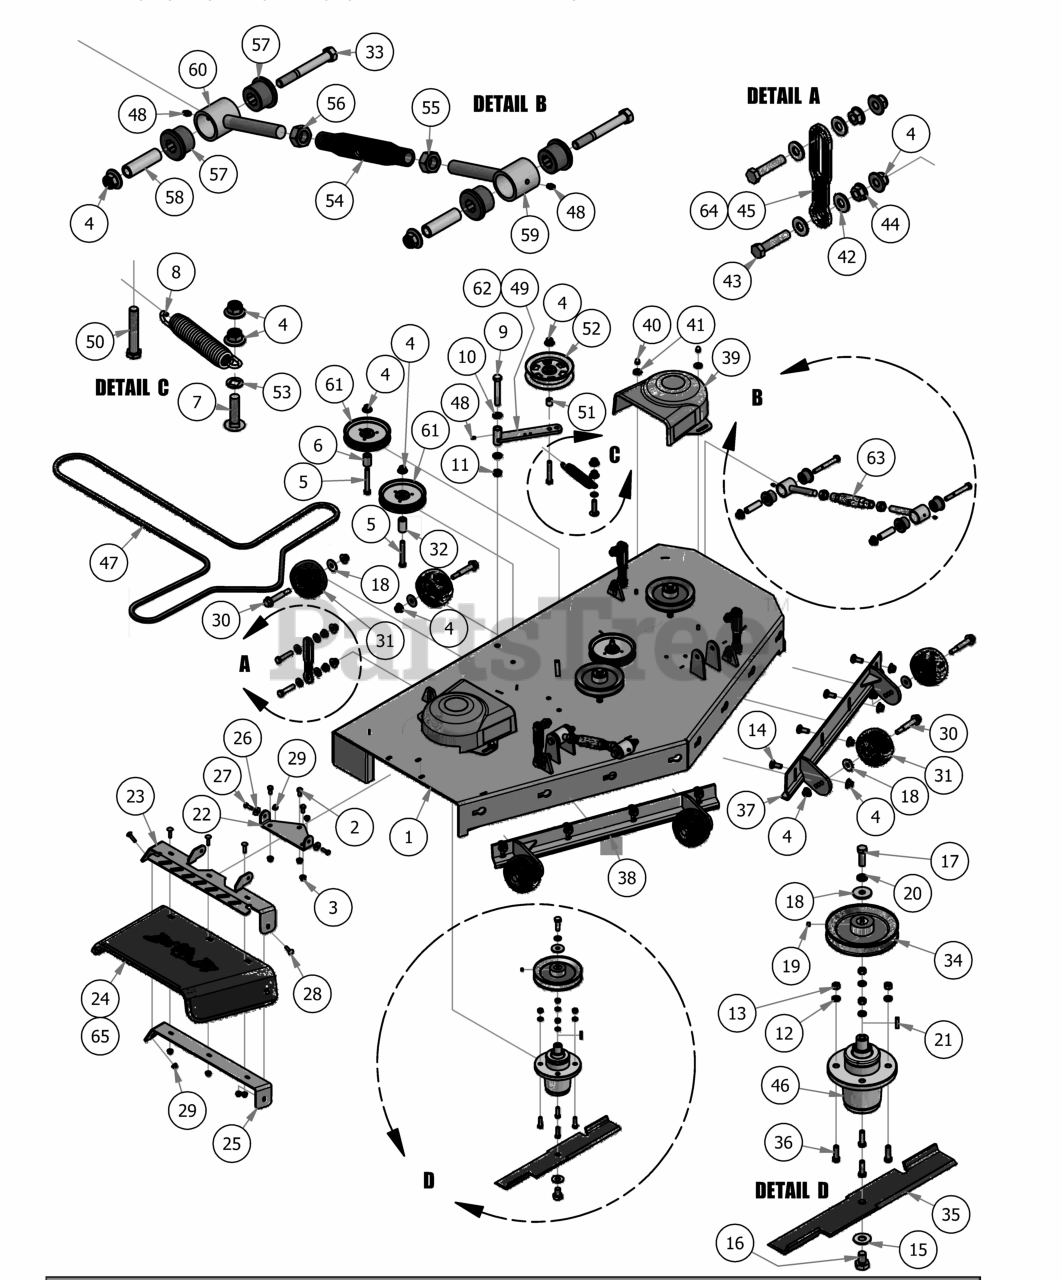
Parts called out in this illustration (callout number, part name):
1	2015 61" Deck
2	3/8" x 3/4" Hex Bolt
3	3/8" Flange Nut
4	1/2-13 Nylon Flange Nut
5	1/2 x 3 1/2 Flange Bolt Grade 8
6	Idler Pulley Standoff
7	1/2 x 2" Carriage Bolt
8	Deck Idler Spring
9	5/8" x 4" Hex Bolt
10	.630 ID Plastic Washer
11	5/8-11 Nylon Insert Jam Half Nut
12	3/8 Lockwasher Zinc
13	3/8-16 Hex Nuts Zinc
14	1/2" x 1 1/4 Carriage Bolt
15	5/8'' Flat Washer
16	5/8" x 1 1/2" Grade 8 Hex Bolt (Fine)
17	1/2"-20 x 1 1/2 - Grade 5 Fine Thread Bolt
18	1/2" Belleville Washer
19	5/16 Set Screw
20	1/2" Lock Washer
21	1/4" x 1" Key
22	Discharge Chute Hanger (deck mounted)
23	60" Discharge Chute Upper Hanger
24	Rubber Discharge Chute
25	60" Discharge Lower Bracket
26	.360 ID Plastic Washer
27	5/16" x 1" Bolt
28	5/16" x 1 1/4" Carriage Bolt
29	5/16" Nylock Flange Nut Zinc
30	Deck Wheel Bolt
31	Anti-Scalp Roller
32	1 3/4" Pulley Spacer
33	1/2" x 4" Bolt (Grade 8)
34	6 1/4" Drive Pulley
35	61 inch Fusion Blade
36	3/8" x 1 1/4" Hex Bolt
37	61 Deck Adustable Front (Left)
38	61 Deck Adustable Front (Right)
39	Pulley Cover
40	Acorn nut-pulley Cover
41	.360 ID Plastic Washer-Black
42	.505 Nylon Spacer
43	1/2-13X 2-1/4 GR Hex Bolts
44	1/2" Flange Nut
45	Deck_Hanging_Tab
46	OUTLAW SPINDLE ASSEMBLY
47	B178 Belt For 61 Inch Outlaw
48	1/4" Press in Grease Fitting
49	Deck Idler
50	1/2-13 x GR 5 Hex Bolt Zinc
51	Spacer 3/4 OD x 1/2 ID x 3\4 Length
52	5" Idler Pully
53	.517 Square Hole Round Washer
54	2015 Outlaw Toplink Body
55	3/4-10 Left-Handed Hex Nuts Zinc
56	3/4-10 Hex Nuts Zinc
59	Turn Left-Handed
60	Right-Handed End
61	5-3/4 Idler Pulley-Capitol Stampings
62	Deck Idler Assembly - Includes parts: 4, 49, 48, 50, 51, 52,
63	Turnbuckle Assembly
64	Outlaw Deck Hanger Assembly - Includes Parts:4,42,43,44,45
65	Chute Assembly - Includes Parts:23,24,25,28,29
